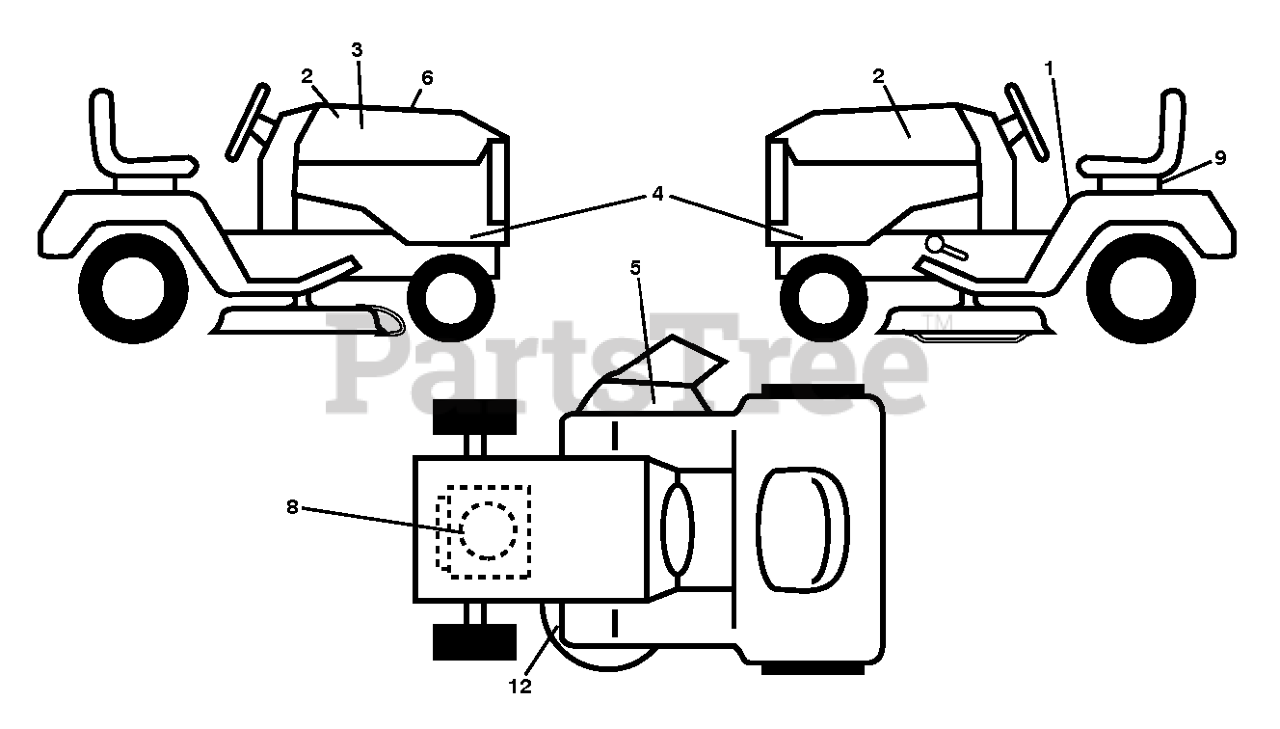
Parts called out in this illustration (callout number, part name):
1	DECAL.FENDER.WARNING.ENGLISH
2	DECAL.BADGE.170MM.TEXTLOGO.
3	DECAL.RPL.BSM33INTK.TLW.38.GEN
4	DECAL TRACTOR SIDE PANEL DECAL
5	DECAL, DECK DEFLECTOR, WARNING
6	DECAL.WARNING.CUST.RESP.E85.
8	DECAL.ENG.BS.18.5INTK.381713
9	DECAL BTRY SYMBOLS
12	DECAL.DECK.SCH.36,38,94.NONCR
